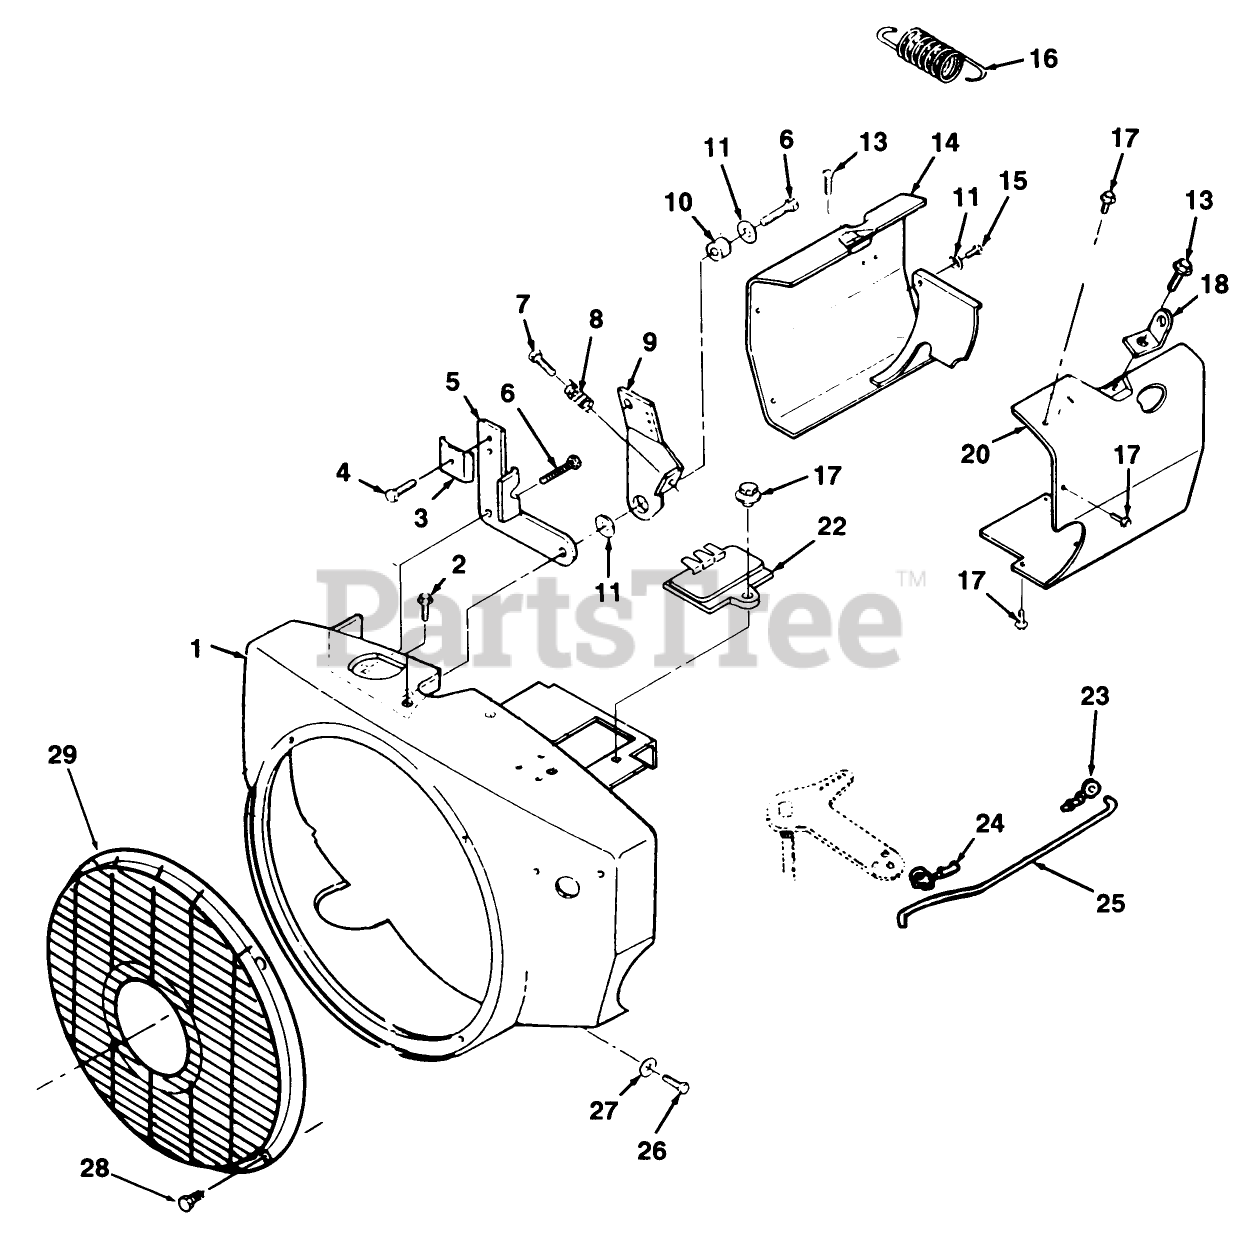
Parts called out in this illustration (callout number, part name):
1	HOUSING - BLOWER
2	SCREW-HWH
4	SCREW-TAPPING
5	BRACKET-GOVERNOR
6	SCREW-HWH
7	SCREW-TAP
8	SPRING
10	BUSHING
11	WASHER-FLAT
13	SCREW-HWH
14	HOUSING - CYL AIR, LH
15	SCREW-HH
16	SPRING
17	SCREW-HWH
18	BRACKET-LIFTING
20	HOUSING - CYL AIR, RH
22	REGULATOR
25	ROD-GOV CONTROL
26	Screw-Tapping
27	WASHER-FLAT
28	SCREW-PAN HEAD
29	GUARD-STATIONARY
